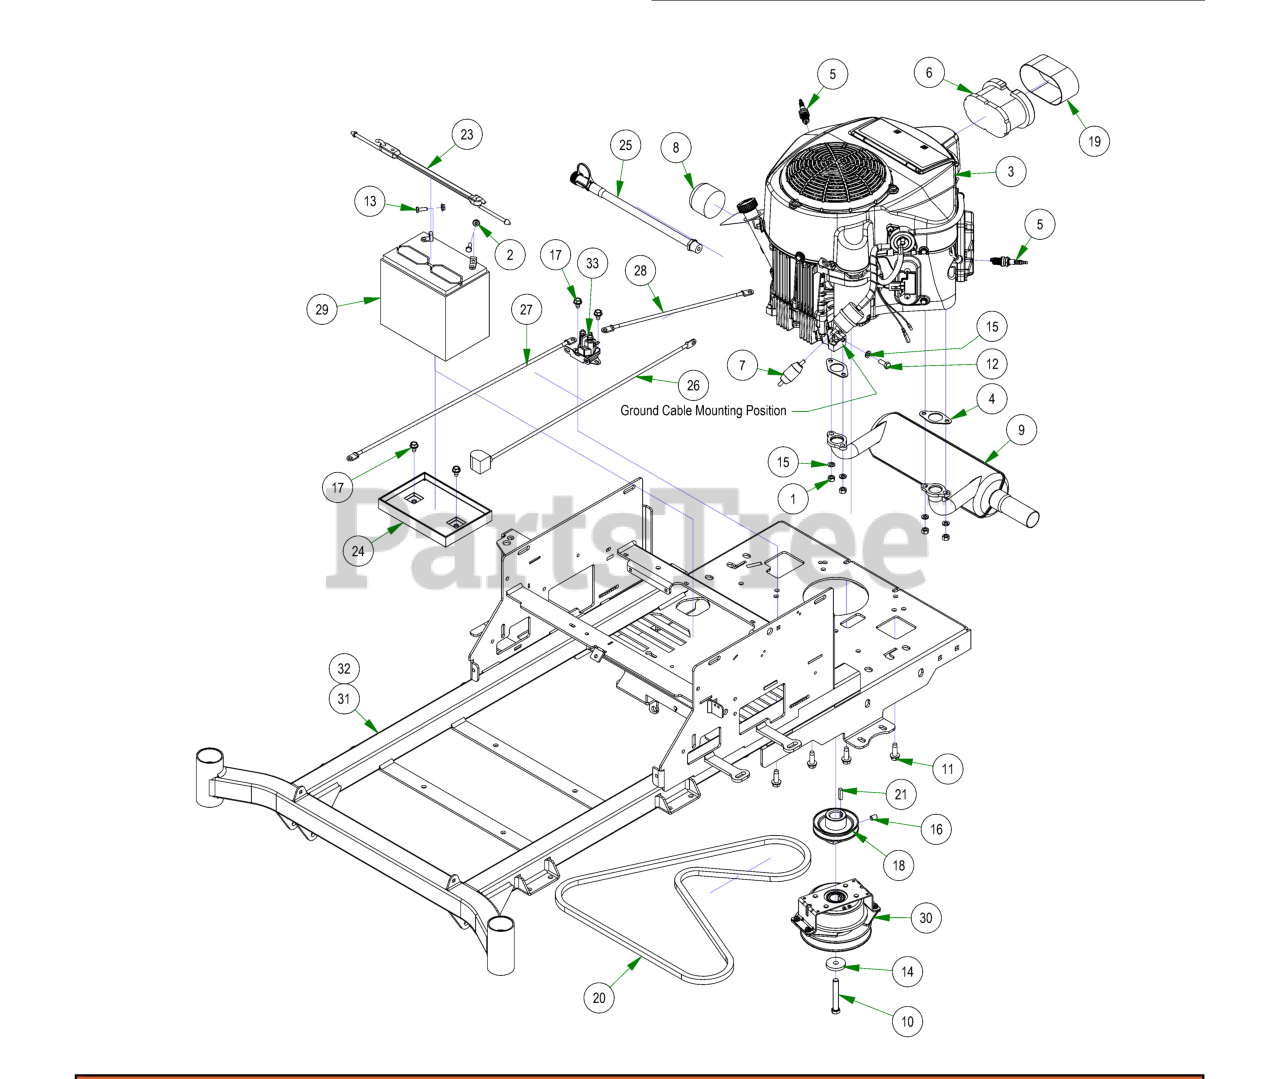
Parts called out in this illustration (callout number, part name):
1	M8-1.25 DIN 934 HEX NUT (CL.8) ZINC
2	1/4-20 HEX SERRATED FLANGE NUT HARD/ZINC
3	726cc Kawasaki Engine-FR651V
4	Exhaust Gasket
5	Spark Plug - Kawasaki
6	Kawasaki Air Filter
7	Universal Inline Fuel Filter
8	Oil Filter
9	Kawasaki Muffler 1251
10	7/16-20x3” Hex Bolt GR 8 W/ Patch
11	3/8-16 X 1-1/8HEX WASHER UNSLOT SERRATED (TRI-LOB) TRS
12	M8-1.25 X 20MM DIN 933 HEX TAP BOLT (CL 8.8) ZINC
13	1/4-20 X 3/4 HEX CAP SCREW (GR.5) ZINC
14	CLUTCH WASHER
15	5/16 SPLIT LOCKWASHER ZINC
16	3/8-16 X 1/2 SOCKET SET SCREW (CUP PT) PLAIN
17	5/16-18 X 1/2 HWH unslot (F) tcs zinc
18	3-3/4" Motor Pulley
19	Air Filter Pre-Cleaner for KAW
21	1/4 X 1 SQ MACHINERY KEY 1018 STL PLN
22	2023 Battery Hold Down Assembly
23	2023 Rubber Battery Hold Down Strap
24	Battery Tray
25	Kawasaki Oil Drain
26	24 inch Black Cable – MZ/ZT
27	24" Red Battery Cable
28	12 in red battery cable
29	SP-35 Battery
31	2024 MZ 42-48 Frame
32	2024 MZ-Avenger 54-60 Frame
